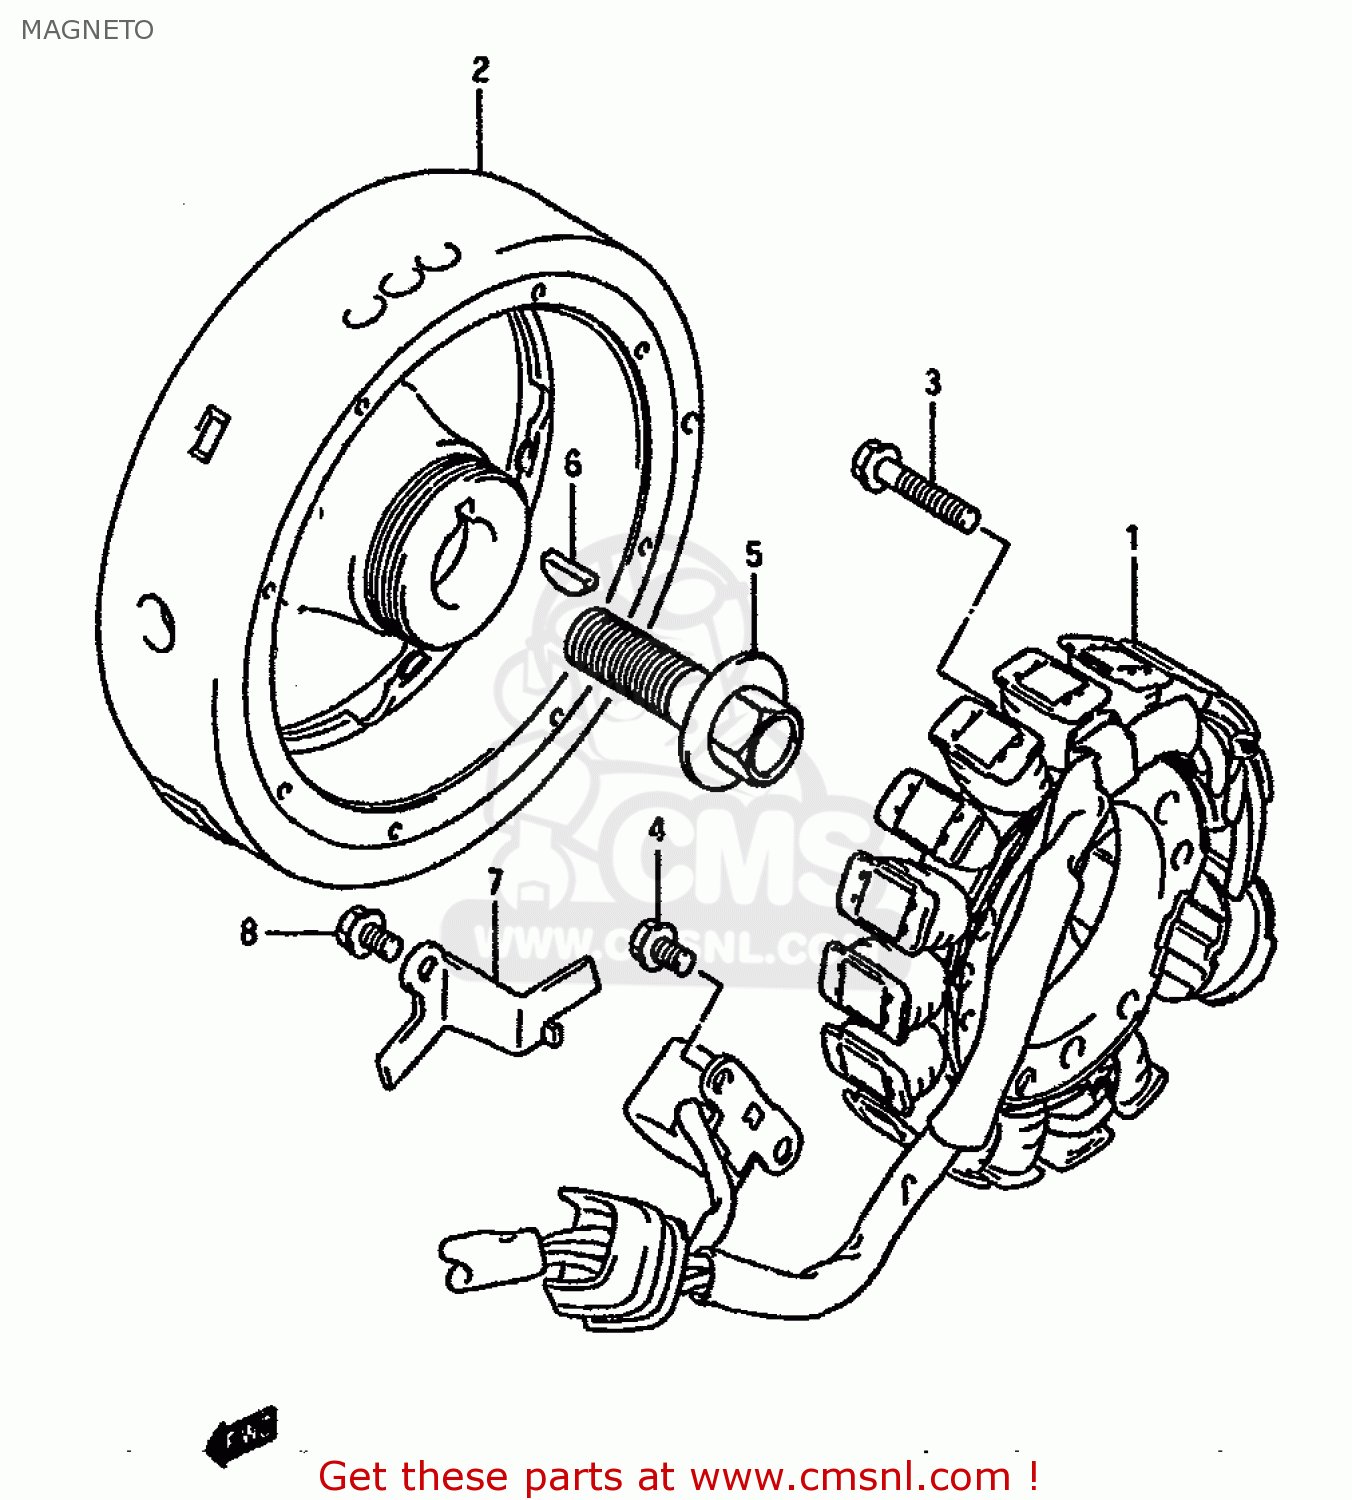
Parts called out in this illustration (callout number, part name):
1	STATOR ASSY
2	ROTOR
3	BOLT
4	BOLT
5	BOLT(14X43)
6	KEY
7	CLAMP,MAGNETO LEAD WIRE
8	BOLT
